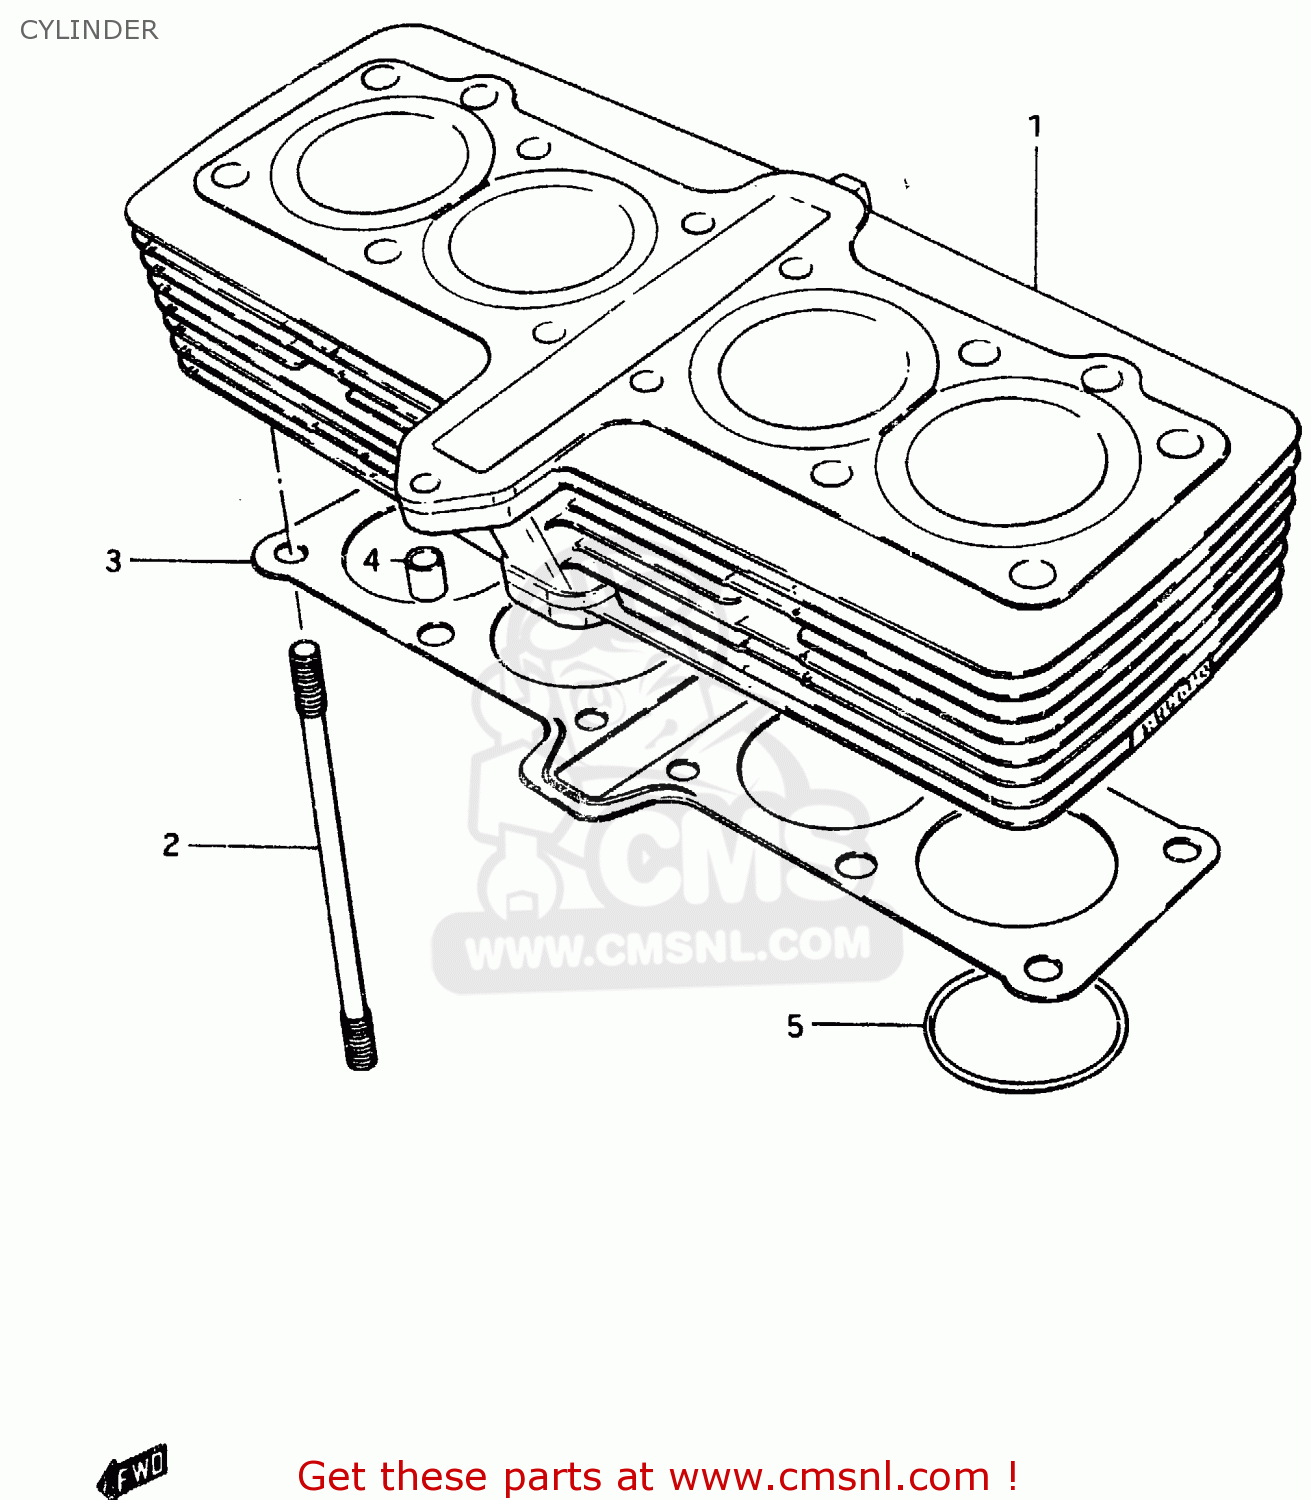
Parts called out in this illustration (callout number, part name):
1	CYLINDER
2	STUD
3	GASKET (T:0.8) (MCA)
4	PIN
5	O-RING (D:2 ID:56.5)
